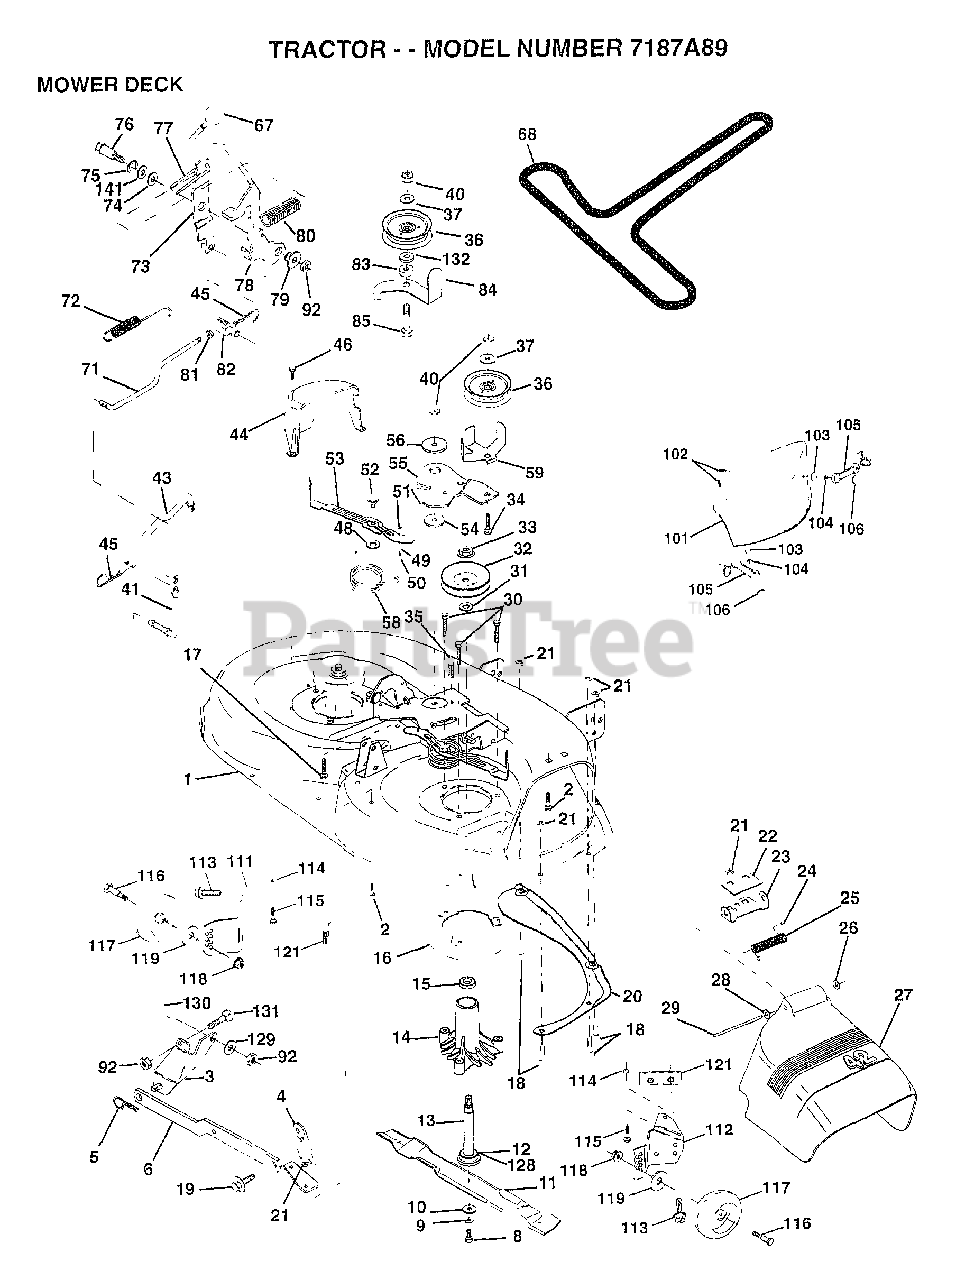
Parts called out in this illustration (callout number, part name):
1	DECK.WELD.42.
2	BOLT
3	BRKT ASM SWAY BAR
4	BRKT DECK SW BAR
8	BLADE BOLT
10	WASHER.HARD.BLADE
11	"BLADE.42"" MULCHER"
12	BEARING.BALL
14	HSG ASM MANDREL
15	BEARING
16	STRIPPER RND MWR
17	BOLT RDHD 3/8-16
18	BOLT
19	BOLT SHD 5/16-18
20	BAFFLE VORTEX 42
22	STIFFENER BRKT
23	DEFLECTOR BRKT
24	CAP-SLEEVE LT
25	SPRING TORSION
27	DEFLECTOR.SHIELD
28	WASHER
29	HINGE ROD
30	"SCREW-THD ROLL,WA"
31	WASHER
32	PULLEY.MANDREL.42
34	BOLT
35	XMAS TREE FASTNER
36	FLAT IDLER PULLEY
37	WASHER
41	PIVOT ROD
43	ROD CLUTCH W/NIBS
44	GUARD MAND LH BLK
46	SCREW.1/4-20X5/8
48	HARD SMALL WASHER
49	ROLLER ASM-CAM
50	SHOULDER BOLT
51	LOCKNUT
52	BOLT.SHLD.5/16-18
54	HARDENED WASHER
55	ARM-IDLER
56	SPACER RETAINER
58	SPRING TORSN BRAK
59	GUARD IDLER TUV
67	KNOB.RD.7/16-14
68	BELT.V.T-PATH
71	ROD CLUTCH 38/42
72	RETURN SPRING
73	CLUTCH ARM SECOND
74	WASHER
75	RING
76	SHOULDER BOLT
77	SPRING KEEPER
78	LEVER.ASM.CLUTCH
79	BUSHING
80	SPRING.CLUTCH.MWR
81	NUT
82	TRUNION ADJ
83	WASHER
84	"KEEPER-BELT,FIXED"
85	BOLT RDHD 3/8-16
92	NUT
101	"COVER.MULCH.42"""
102	SCREW
103	WASHER #10
104	LOCKWASHER
105	LATCH ASSY.BAGGER
106	WELDNUT
111	BRACKET.GWHL.LH.
112	BRACKET.GWHL.RH.
113	SCREW
116	BOLT.SHOULDER
117	WHEEL GAGE DONUT
118	LOCKNUT
119	WASHER
121	BRACKET.EXTRD.GWL
128	WASHER.FELT.
129	WASHER
130	BOLT
132	WASHER GT
